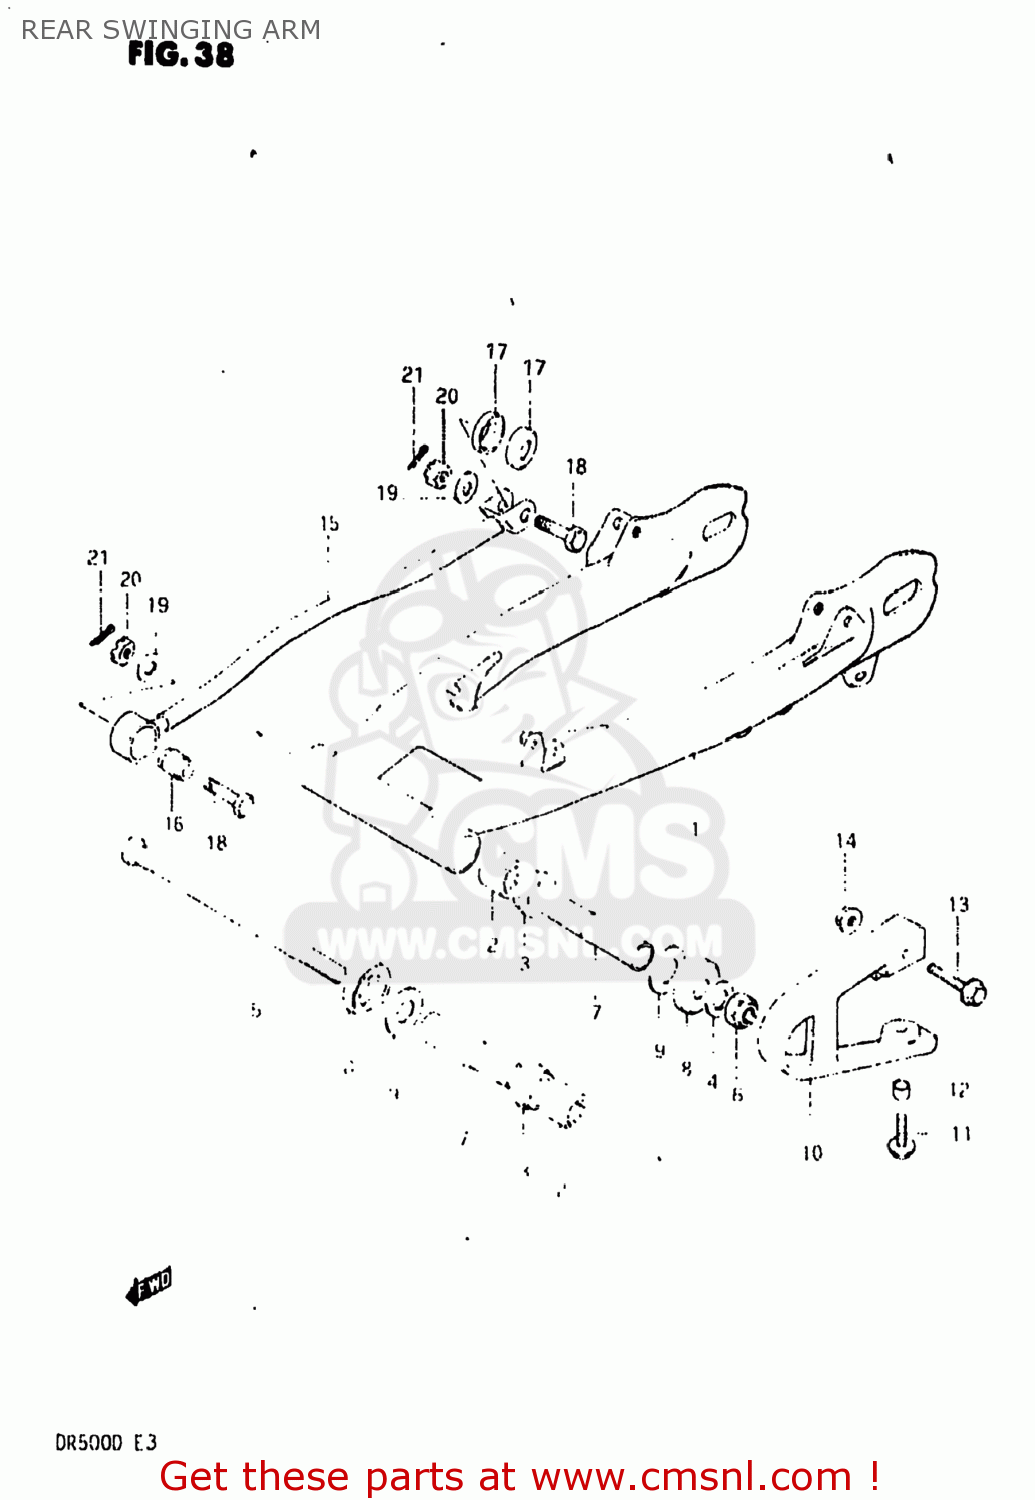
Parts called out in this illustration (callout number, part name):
1	SWING ARM ASSEMBLY,REAR
2	BEARING
3	BUSHING,REAR SWING ARM PIVOT
4	WASHER
5	SHAFT,REAR SWING ARM
6	NUT 16MM
7	SPACER,REAR SWING ARM
8	COVER,REAR SWING ARM DUST
10	BUFFER,CHAIN TOUCH DEFLECTOR
11	SCREW,CHAIN TOUCH DEFEND
12	SPACER (5.5X8X4)
13	BOLT,UNDER
14	NUT
15	LINK,REAR TORQUE
16	BUSH
17	18
18	BOLT 8X29.5
19	WASHER
20	NUT 8MM
21	PIN 20X20
